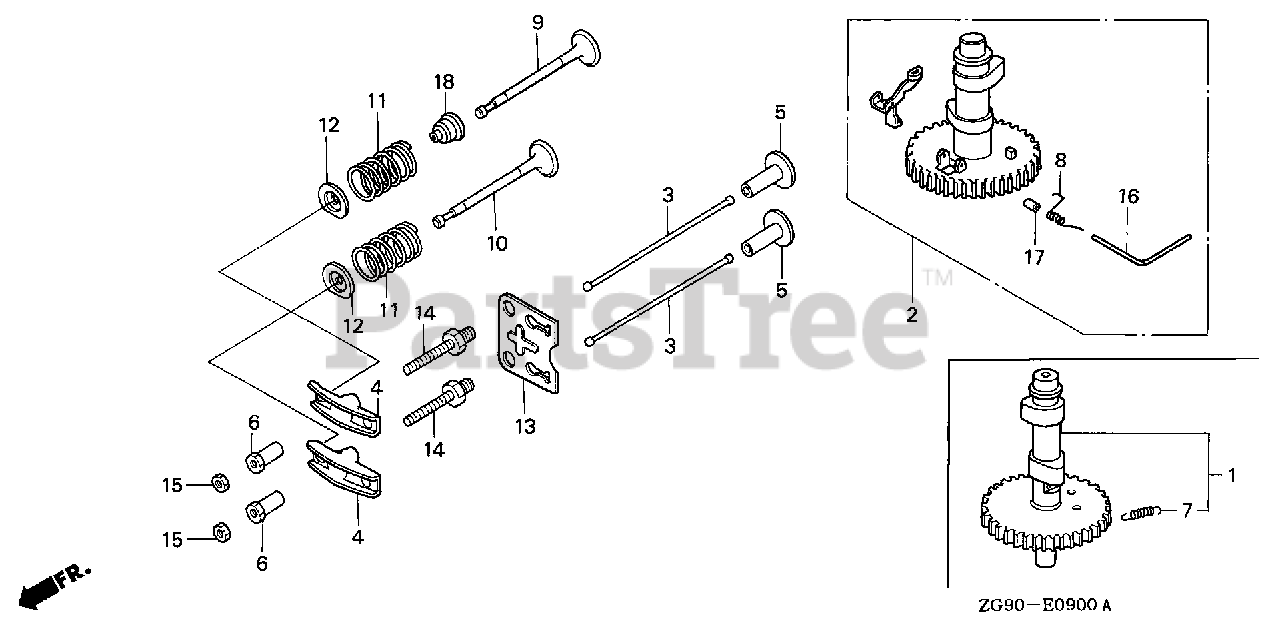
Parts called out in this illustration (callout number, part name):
2	CAMSHAFT ASSY.
3	ROD, PUSH
4	ARM, VALVE ROCKER
5	LIFTER, VALVE
6	PIVOT, ROCKER ARM
8	SPRING, WEIGHT RETURN
9	VALVE, IN.
10	VALVE, EX.
11	SPRING, VALVE
12	RETAINER, IN. VALVE SPRING
13	PLATE, PUSH ROD GUIDE
14	BOLT, PIVOT (8MM)
15	NUT, PIVOT ADJUSTING
16	PIN, WEIGHT CENTER
17	COLLAR, WEIGHT CENTER
